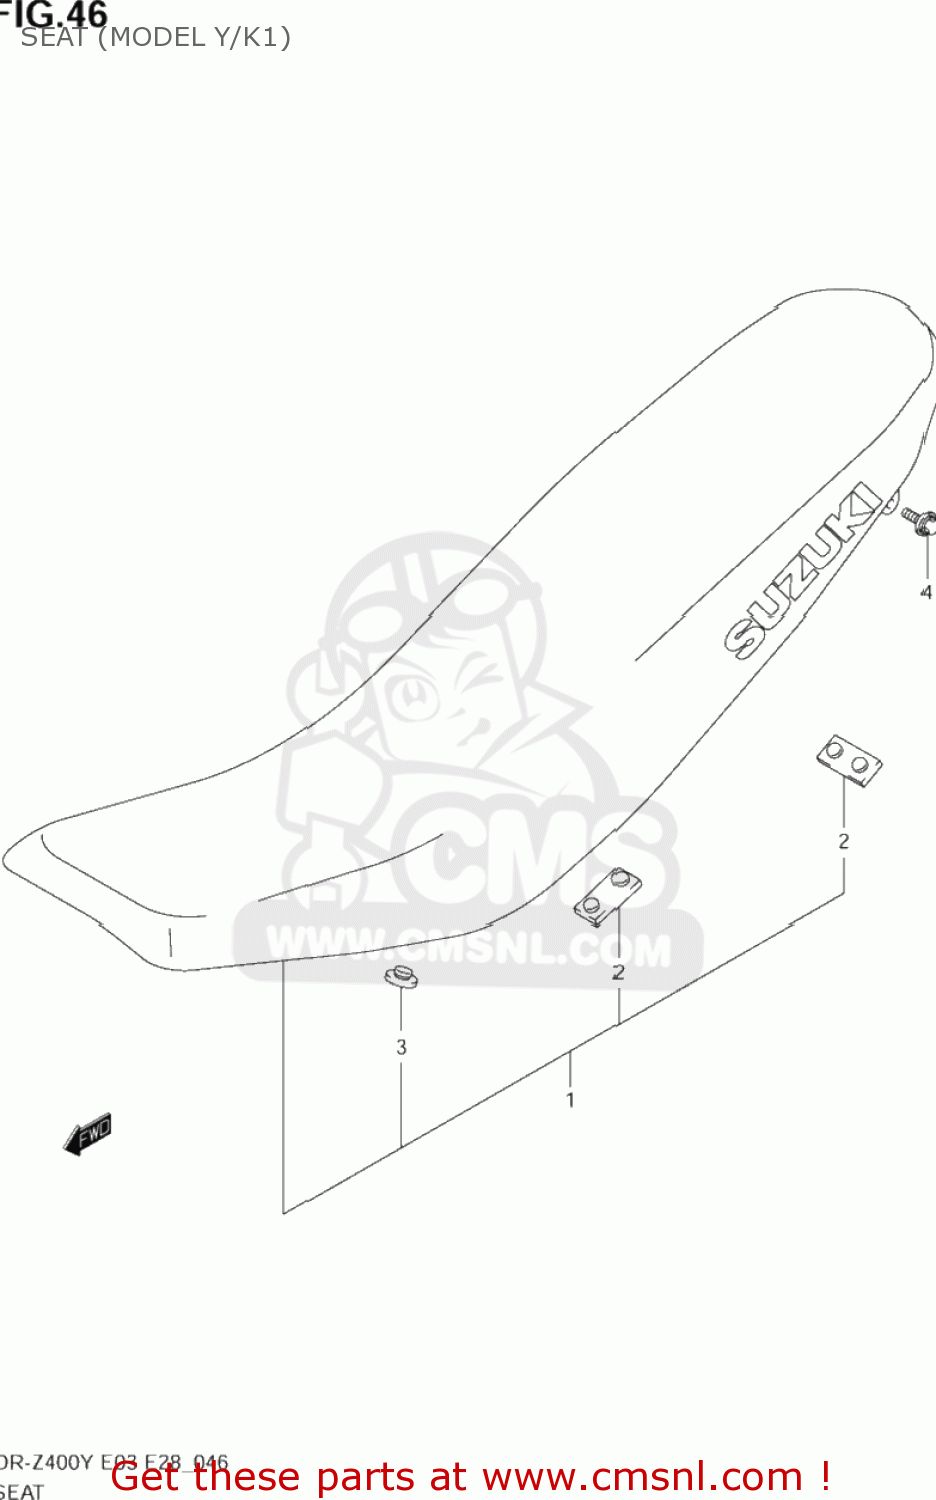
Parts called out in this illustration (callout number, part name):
1	SEAT ASSY
2	CUSHION,SEAT(40X20X6)
3	CUSHION
4	BOLT(6X20)
